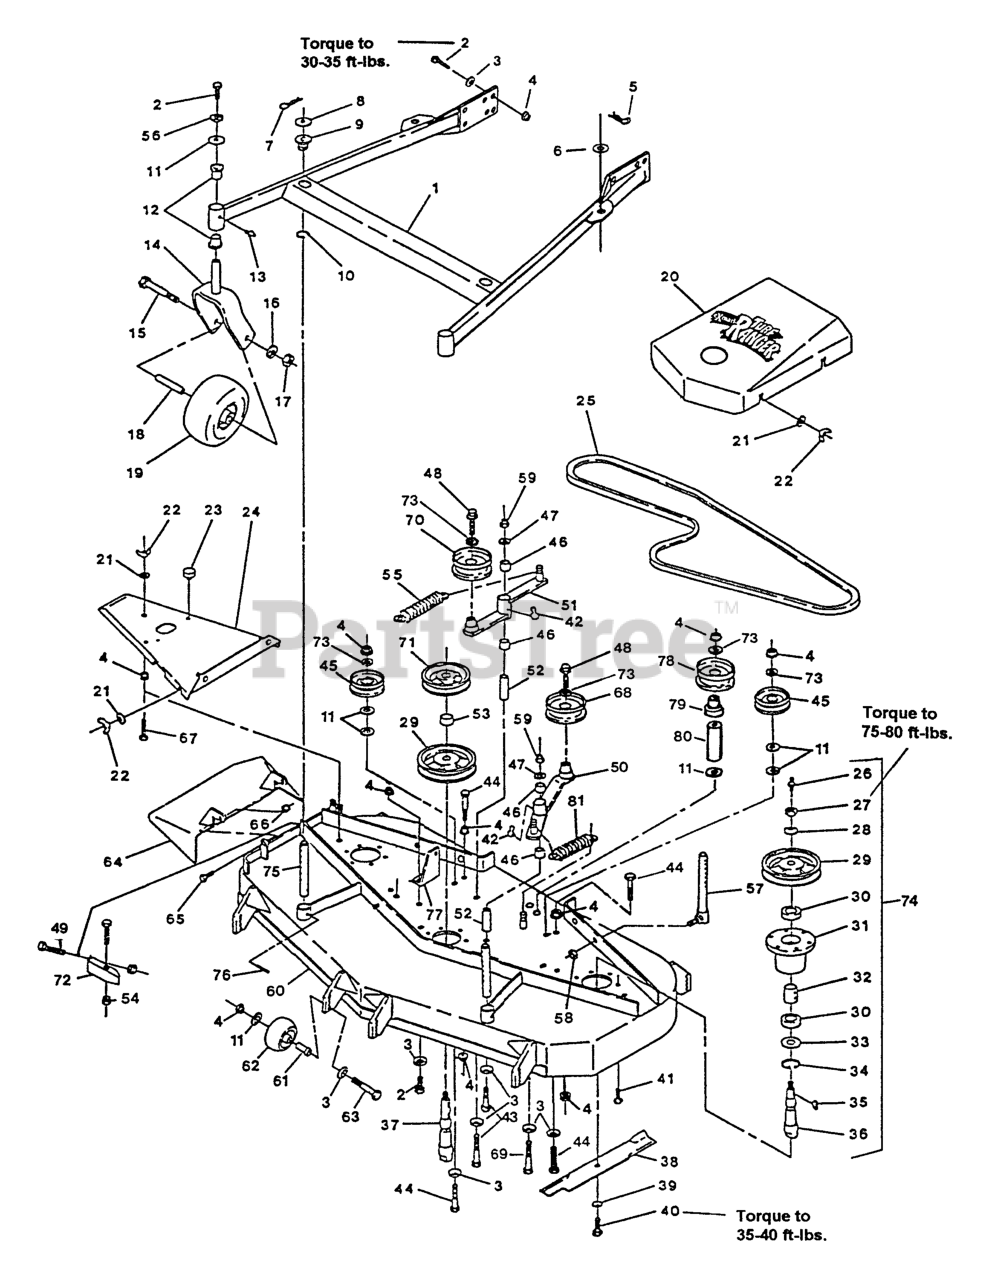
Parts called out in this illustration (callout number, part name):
1	SUPPORT ASSY-FMD60
5	PIN,HAIR COTTER
8	WASHER-FLAT
9	BUSHING-DECK
11	WASHER
12	BEARING-FLANGED
22	NUT-WING
24	WLD,DECK COVER
25	BELT-DRIVE, BLADE
28	WASHER-SPRING
29	SHEAVE,BLADE DRIVE
30	BEARING,HD SPINDLE
32	SPACER,BEARING
33	SEAL,MECHANICAL DUST
34	RING,SNAP WLDS N5000-244
36	SPINDLE-OUTER BLADE
37	SPINDLE-CENTER BLADE
39	WASHER-SPRING
41	SCRW,TPTTE HH
43	SCREW-HH
45	IDLER,PULLEY
46	SLEEVE-BEARING
50	Arm, Deck Drive Idler
51	Arm, Deck Idler
52	BUSHING-PIVOT, IDLER
53	SPACER-TUBE
55	SPRING-EXTENSION
61	BUSHING-ROLLER
62	ROLLER-SCALP, ANTI
68	PULLEY-IDLER
70	IDLER,PULLEY
72	WLD,BAFFLE DISCHARGE
74	CH-52&60 OUTER CUTTR
75	ROD,DECK SUPPORT
77	BRACKET,SPRING ANCHOR
78	PULLEY-IDLER
79	BUSHING,IDLER
80	SPACER-FENDER
81	SPRING-EXTENSION
